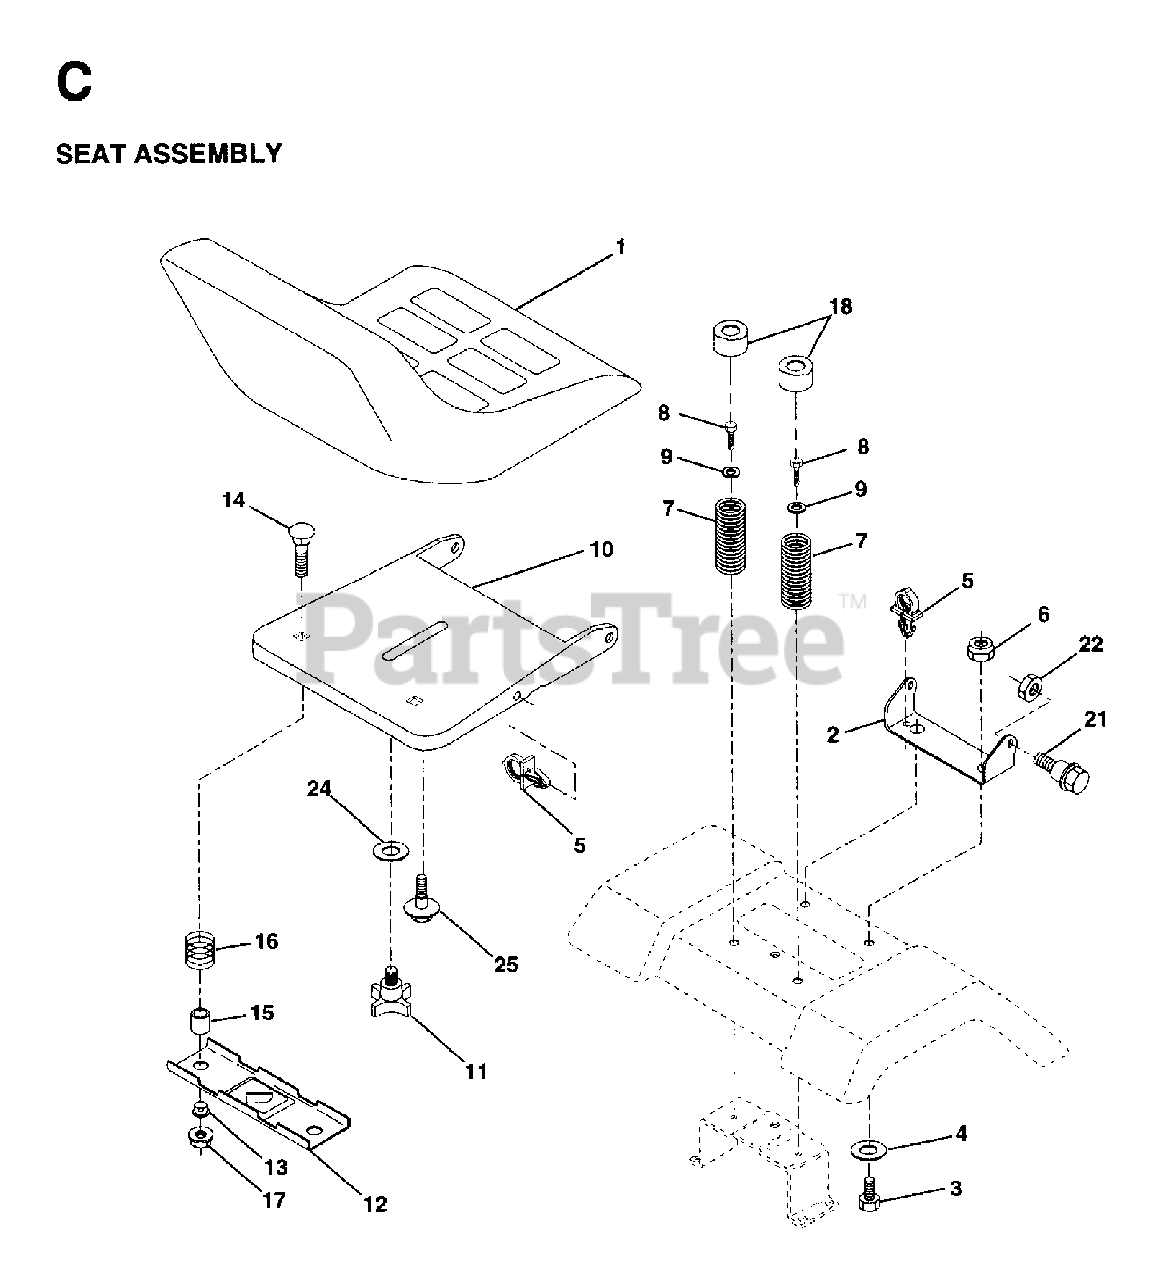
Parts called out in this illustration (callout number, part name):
1	SEAT
2	SEAT PIVOT BRKT
3	BOLT
4	WASHER PM
5	PUSH CLIP
6	NUT
7	SPRING COMPRESSION
8	SCREW GTV
9	WASHER
10	SEAT PAN
11	KNOB 1/2" YT
12	BRKT SWITCH
14	BOLT CARRIAGE 1/4-20X1 3/8
15	SPACER SPLIT
16	SPRING COMPRESSED
17	NUT T
18	CAP SPRING
21	BOLT SHOULDER 5/16-18
22	LOCKNUT
25	BOLT,SHOULD
